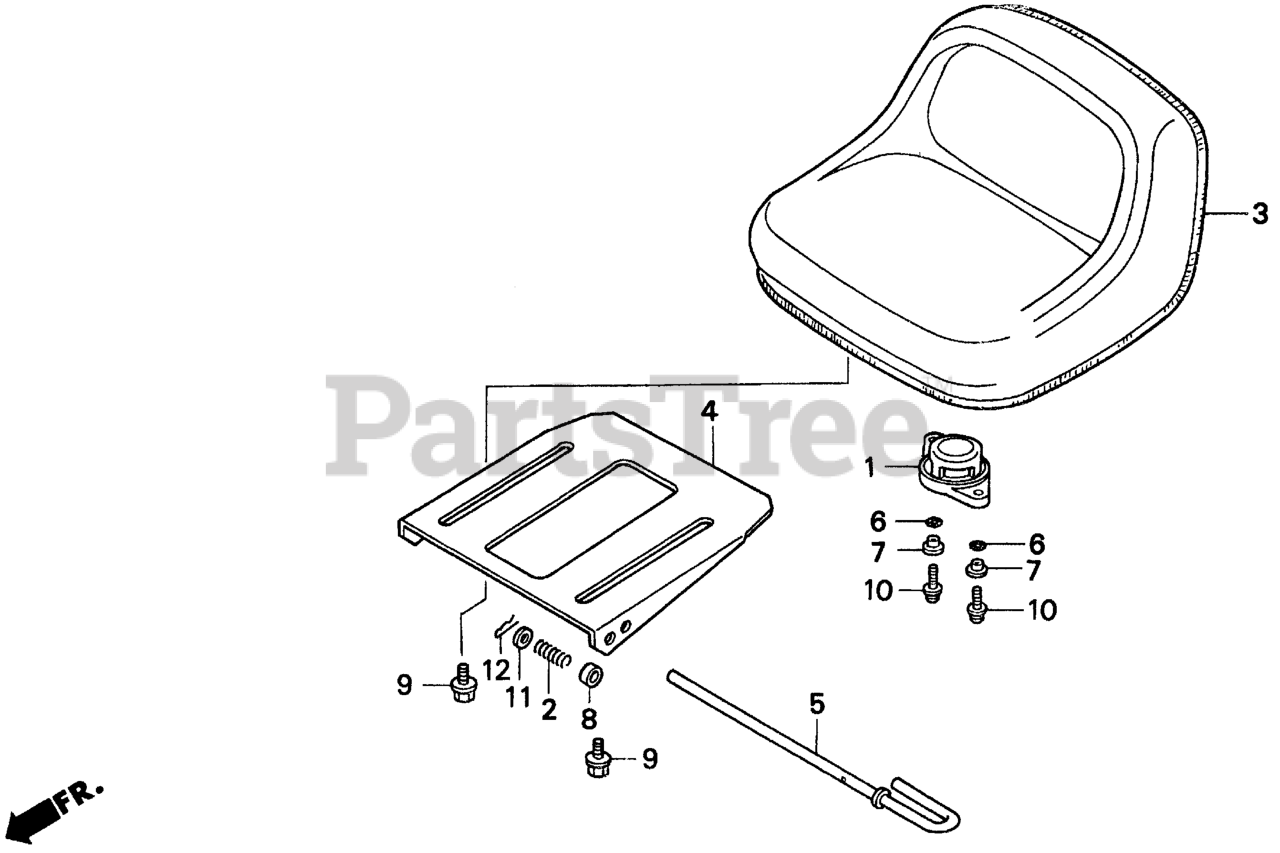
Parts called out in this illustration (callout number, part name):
1	SWITCH ASSY., SEAT
2	SPRING, MAINTENANCE COVER
3	SEAT ASSY.
4	BASE, SEAT
5	PIN, SEAT HINGE
6	O-RING (7.8X1.9) (NOK)
7	COLLAR, SEAT SWITCH
9	BOLT-WASHER (8X16)
10	SCREW-WASHER (5X16) Use up to Engine SN 2056819.
11	WASHER, PLAIN (8MM)
12	PIN, LOCK (8MM)
